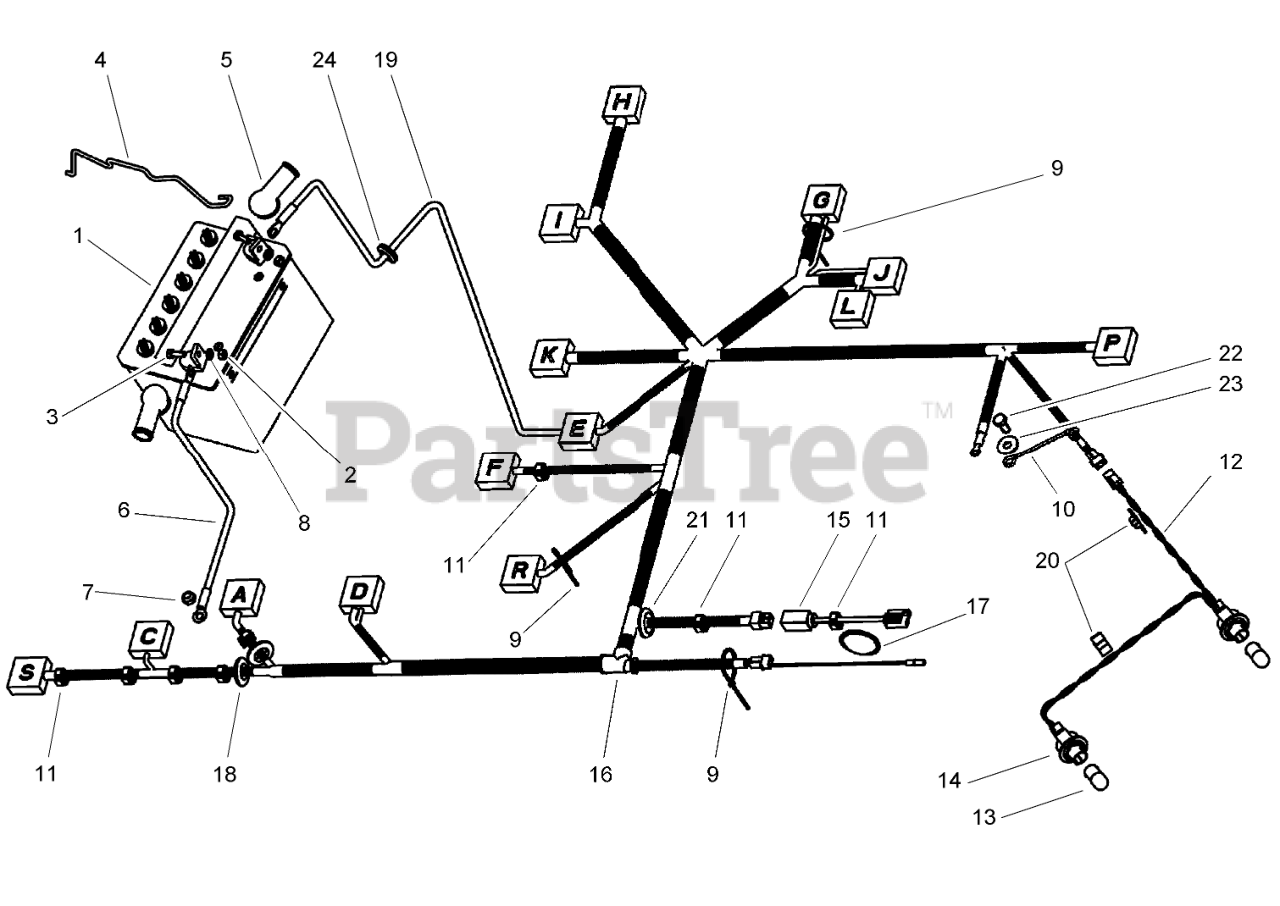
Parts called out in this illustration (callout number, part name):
1	BATTERY-12V
2	NUT-HEX
3	SCREW-HH
4	CLAMP-BATTERY
5	BOOT-RUBBER
6	CABLE-BATTERY, Negative
7	NUT-LOCK, NI
8	WASHER-FLAT
9	TIE-CABLE
10	HOLDER-HARNESS, WIRING
11	CLIP-SNAP
12	HARNESS-WIRE, LIGHTS
13	BULB-LIGHT
14	SOCKET-LIGHT
15	HARNESS-CLUTCH
16	HARNESS-WIRING
18	BUSHING
19	CABLE-BATTERY POSITIVE
20	CLIP-NYLON
21	BUSHING
22	SCREW-HH
23	WASHER-PLAIN
24	GROMMET
